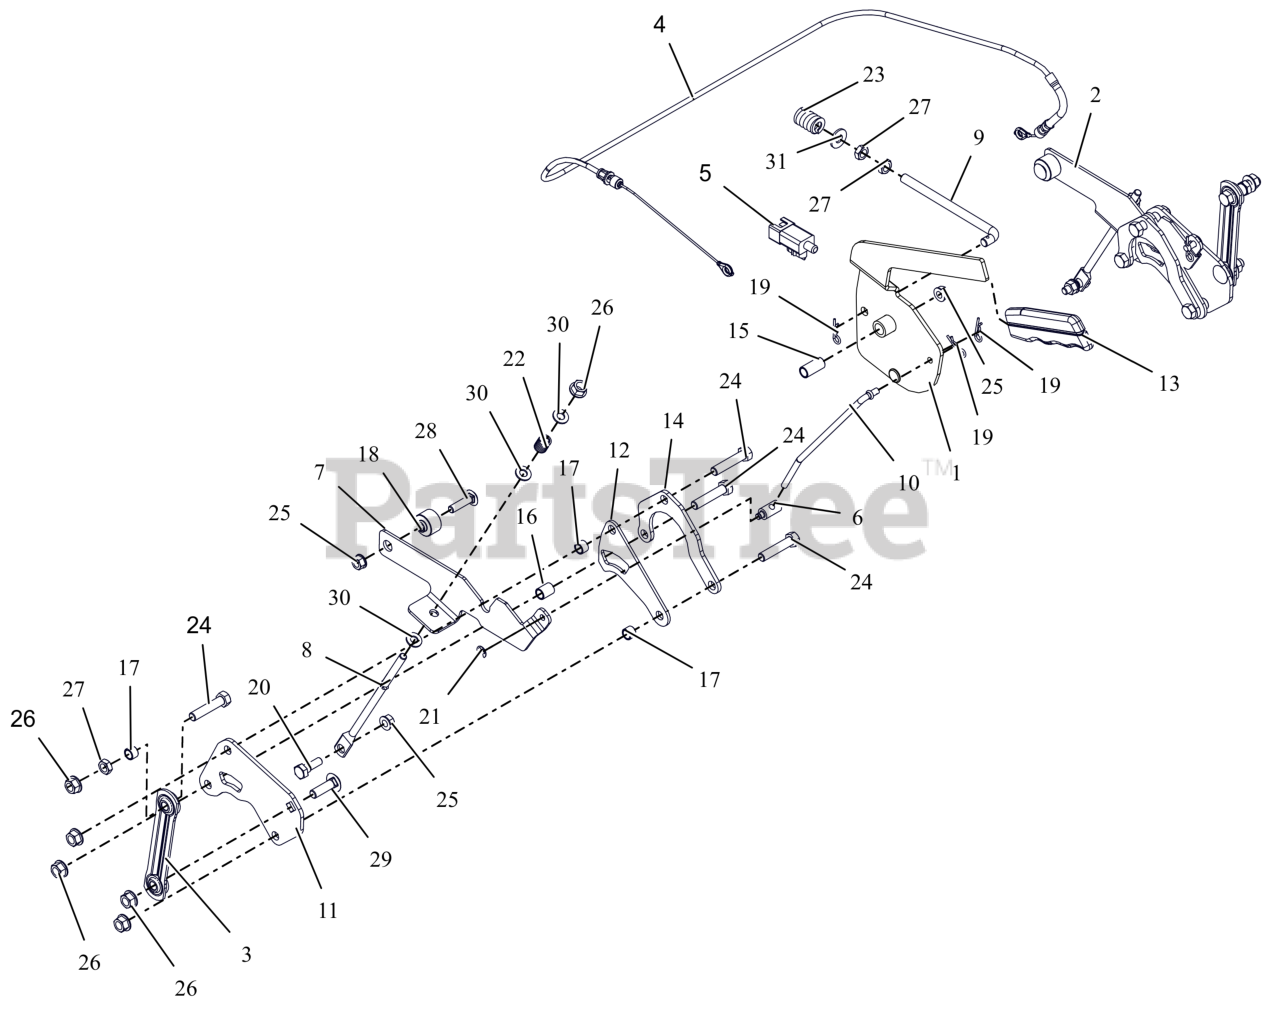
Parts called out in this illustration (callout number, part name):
1	LEVER, PARKING BRAKE
2	ARM, BRAKE - LH (W/PIN)
3	LINK, STAMPED STEERING
4	CABLE, BRAKE - PARKING
5	SWITCH, SNAP IN - N.O./N.O.
6	TRUNION, 1/4-20
7	ARM, BRAKE-RH
8	ROD, LINK - TRANSMISSION BRAKE
9	ROD, OVER CENTER
10	ROD, BRAKE LINK
11	BRKT, TRANSAXLE STEERING
12	BRKT-SPACER
13	GRIP, PARKING BRAKE (YELLOW)
14	PLATE, REAR REINFORCING
15	BSHG-SLV .385X.500X1.045
16	SPCR, SLV .385X.500X.652
17	SPCR, SLV .385X.500X.350
18	SPCR, FLANGE
19	PIN, HAIR #213 .08X1.19 ZCC
20	BOLT,SHLDR .38X.25 -.31-18X.75
21	RG-RTNG-EXT .250X.025
22	SPRING, COMPRESSION
23	SG-COMP .187X.56X1.62
24	BLT, HEX .38-16X1.75 G5 ZCC
25	NUT-LK-TOP-FLG .312-18 GF ZCC
26	NUT-LK-TOP-FLG .38-16 ZC120
27	NUT-JAM .375-16 G2 ZCC
28	BLT, RHSSN.31-18X1.25 G5 ZCC
29	BLT,RHSSN .38-16X1.25 G5 ZCC
30	WSHR,FLT .344X.688X.065 ZCC
31	WSHR,FLT .375X.875X.083 ZCC
